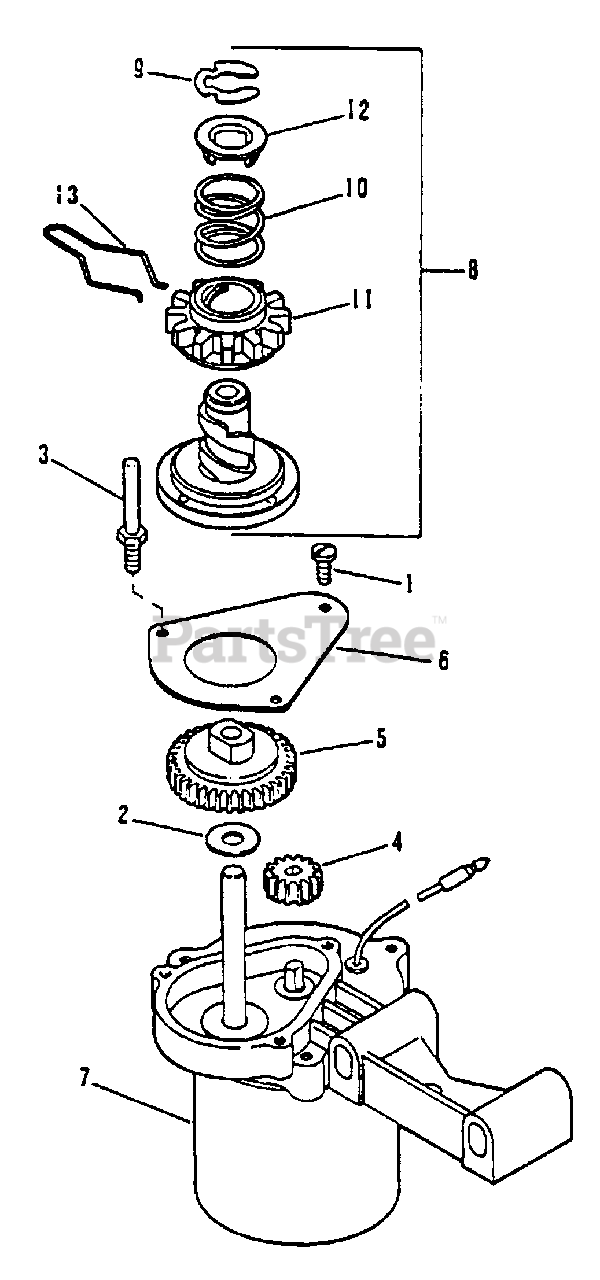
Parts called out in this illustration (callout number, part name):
1	Screw
2	Washer-Thrust
3	Stud-Drag Spring
4	Pinion
5	Gear-Driven
6	Plate-Gear Cover
7	Motor Housing & Pin Assy
8	Pinion, Spring & Clutch Assy (Inc. 9-13)
9	Retaining Ring
10	Spring-Pinion
11	Pinion
12	Stop Washer
13	Spring-Drag
